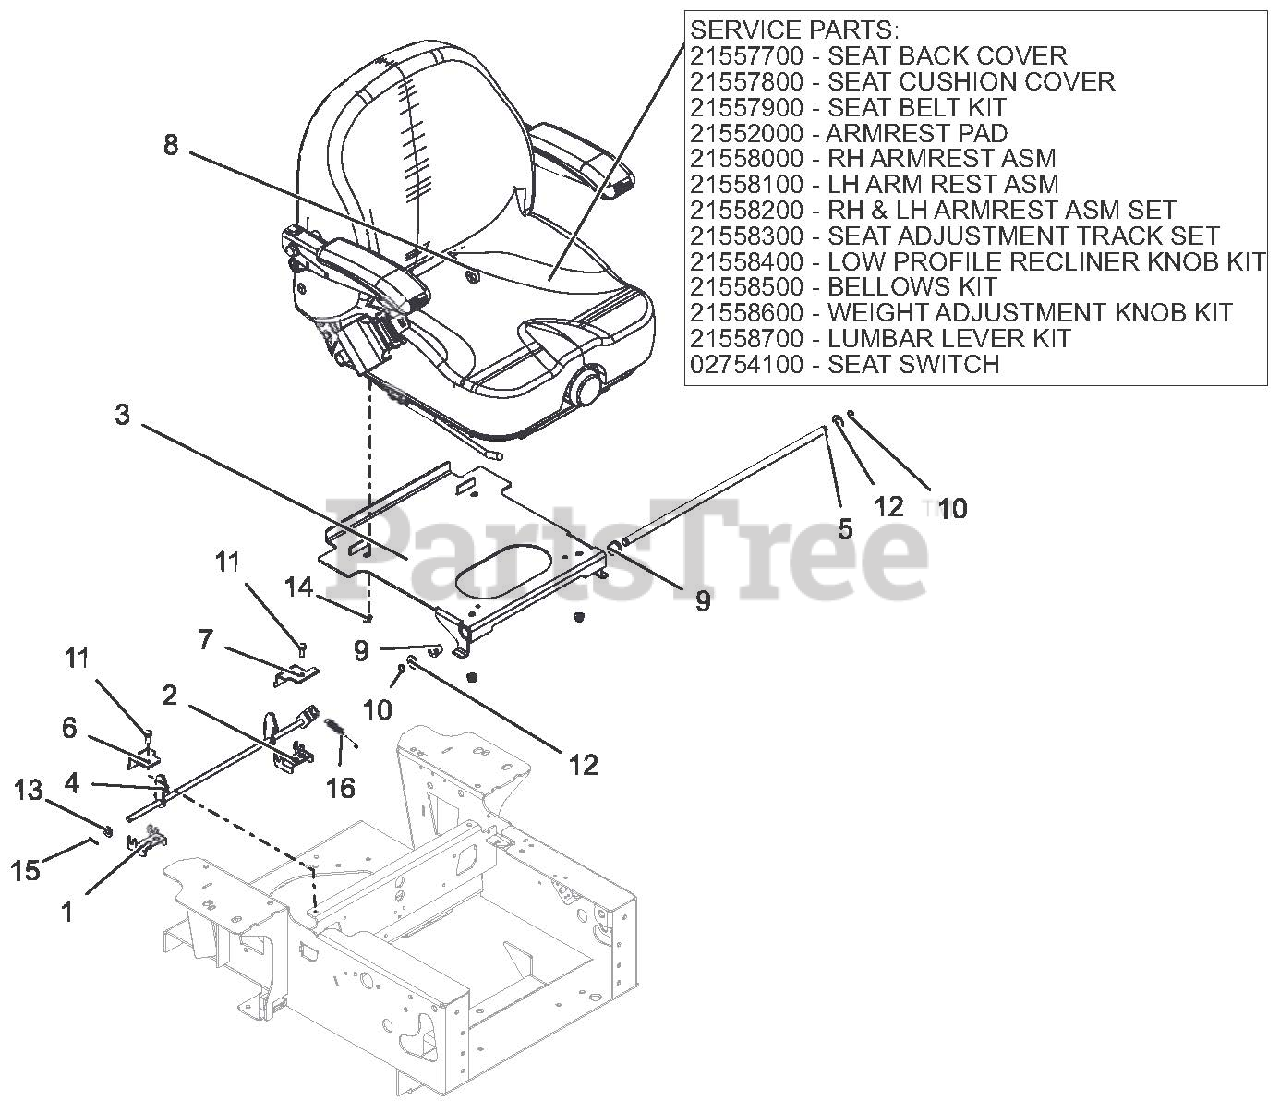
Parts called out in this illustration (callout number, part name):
1	WLDMT, PT/PT100 RH SEAT LATCH MOUNT-BLACK
2	WLDMT, PT/PT200 LH SEAT LATCH MOUNT-BLACK
3	WLDMT, PRO-TURN 100 SEAT PLATE
4	WLDMT, PRO-TURN 100 SEAT LATCH
5	SHAFT, PT/PT100 SEAT PIVOT
6	MOUNT, PT/PT100 RH TOP SEAT LATCH
7	MOUNT, PT/PT100 LH TOP SEAT LATCH
8	SEAT, FULL SUSPENSION
8	SEAT BACK COVER
8	SEAT CUSHION COVER
8	SEAT BELT KIT
8	ARMREST PAD
8	RH ARMREST ASM
8	LH ARM REST ASM
8	RH & LH ARMREST ASM SET
8	SEAT ADJUSTMENT RRACK SET
8	LOW PROFILE RECLINER KNOB KIT
8	BELLOWS KIT
8	WEIGHT ADJUSTMENT KNOB KIT
8	LUMBAR LEVER KIT
8	SEAT SWITCH
9	BSHG, SHLDR EP .358-16 X .30 HEX YZ
10	RG-RTNG-EXT .500 X .050
11	BLT-HEX .31-18 X .75 GR5 YWZC
12	WSHR-FL-STL .531 X 1.000 X .063 YWZC
13	WSHR-FL-STL .406 X .812 X .065 YWZ
14	NUT-LK-NYL-FLG .31-18 YWZC
15	@PIN-CTR .09 X .75 EXTPRSQCT YWZ
16	SPRG, EXTENSION
